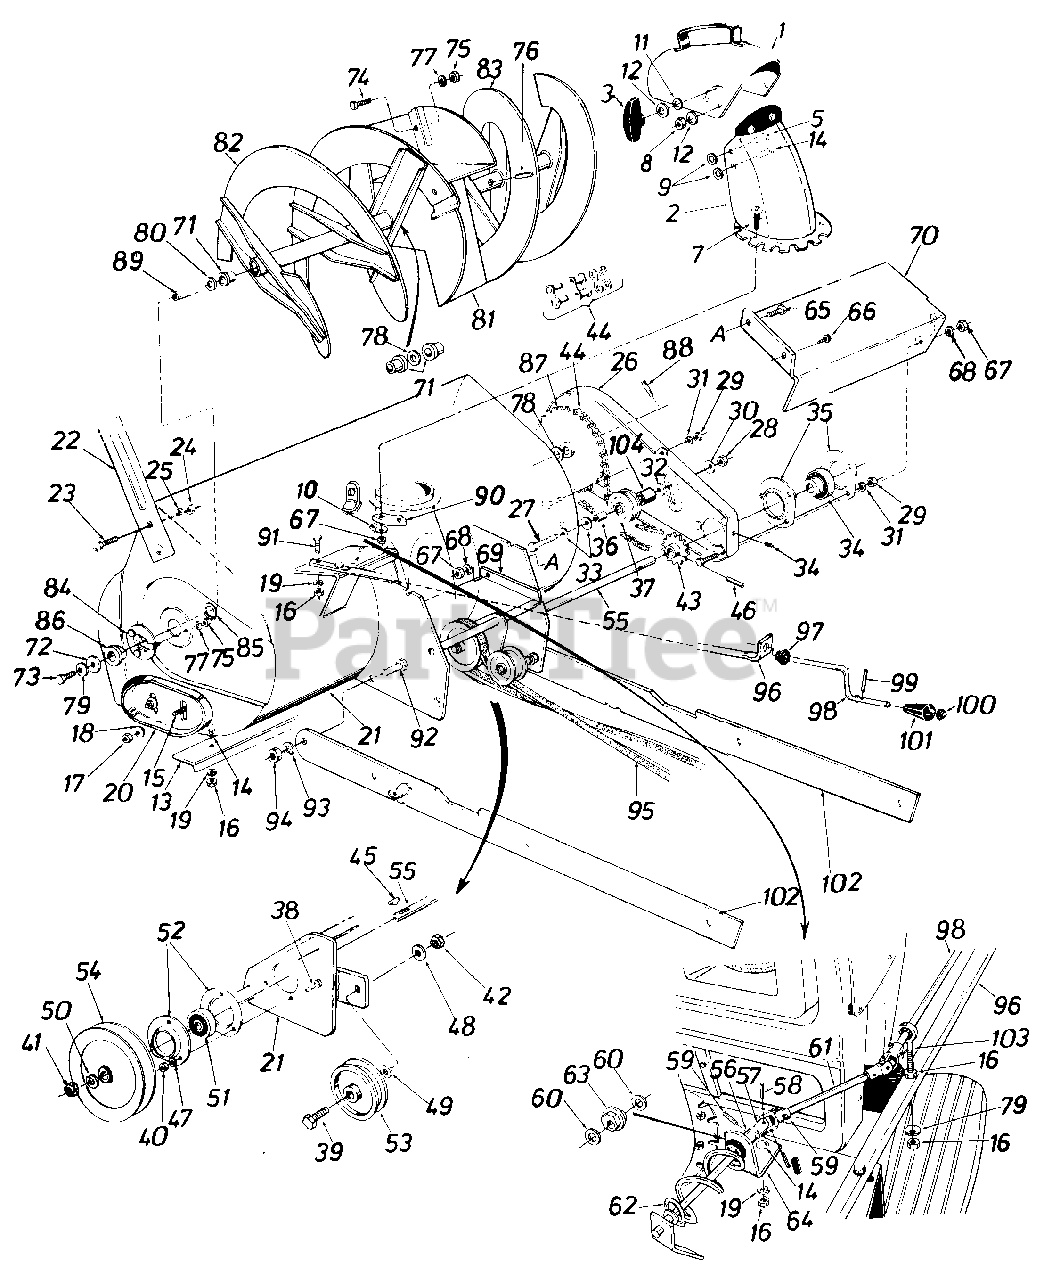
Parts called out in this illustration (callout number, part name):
1	Top Chute Ass'y.
2	Chute Assy w/ Guard
3	Knob Handle Ass'y,
5	Carriage Bolt 5/l6-18 x 1.0" Lg.'
7	Truss Mach. Scr. 1/4-20 x .75" Lg.
8	Hex Cent L-Nut 5/16-18 Thd.
9	Fl.Wash. 531" I.D. x 1.25" O.D.
10	Bell Wash 1/4" I D
11	Fl Wash 344 1 D x 1.125" o.D
12	Bell Wash. 345" 1 D. x .88" 0D.
14	Carriage Bolt 5/16-18 x .62" Lg.
15	Carriage Bolt 3/8-16 x .62" Lg.*
16	Hex Nut 5/16-18 Thd.'
17	Hex Jam Nut 3/8-16 Thd.
18	Bell. Wash. .400" I.D. x .88" O.D.
19	L. Wash. 5/16" I.D.'
20	Slide Shoe
21	Spiral Hsg. Ass'y.-36"
22	Guide Blade
23	Carriage Bolt 5/16-18 x .62" Lg.'
24	Hex Nut 5/16-18 Thd.'
25	L.-Wash. 5/16" I.D.'
26	Chain Guard Ass'y.
27	Hex Bolt 3/8-16 x 2.00 Lg.'
28	Hex Inst.-Nut 3/8-16 Thd.
29	Hex Nut 5/16-18 Thd.'
30	Bell.-Wash. .400" I.D. x .88 O.D.
31	L.-Wash. 5/16" I.D.'
32	Fl.-Wash. .406" I.D. x 1.25" O.D.
33	Fl-Wash. .385" I.D. x .87" O.D.
34	Ball Brg. .75" I.D.
35	Flangette
36	Spacer .375" I.D. x .60" O.D.
37	Fl.-Idler w/Flanges 1.875 O.D. Plastic
38	Hex Sems Bolt 5/18 x .75" Lg.
39	Hex Bolt 3/8-16 x 1.75" Lg.'
40	Hex Nut 5/16-18 Thd.'
41	Hex Jam Nut 3/4-10 Thd.
42	Hex Jam Nut 3/8-16 Thd.
43	Sprocket Ass'v.-14 Teeth
44	4420 Chain x 112" Pitch 78 Links
45	461 Hi- Pro-Key 3/16 x 518" Dia.
46	Spring Pin Spir. 5/16" Dia. x 1.75" Lg.
47	L.Wash. 5/16" 1 D.'
48	L.-Wash. 3/8" I.D.'
49	Fl.-Wash .406" 1 D x 125 ' O.D
50	Spring L.-Wash 314' I.D.
51	Self-Aligning Brg.
52	Flangette
53	Idler Pulley
54	5/8 V Pulley 75 ' ' D x 6.0"O.D.
55	Drive Shaft Assv
56	Joint Brkt. Ass'y
57	Joint Block
58	Oval Head Rivet
59	Spirol Pin 1/8 Dia x .812" Lg .
60	Fl.Wash .385 I.D. x .62" O.D.
61	Chute Crank Ext Rod 3/8" Dia. x 60 Lg
62	Chute Crank Ass y. R H 6-1/4 Lg
63	Plastic Bushing .380 1 D
64	Chute Crank Brkt
65	Hex Bolt 1/4 20 x .62" Lg '
66	Hex Wash S-Tap Scr 1/4 20 x -50" Lg
67	Hex Nut 1/4 20 Thd'
68	L-Wash- 1l4" 1 D'
69	Belt Cover
70	Drive Shaft Cover
71	Plastic Bushing
72	Washer 39' I-D x 1-,75" O-D
73	Hex Bolt 5/16-18 x -88" Spec
74	Carriage Bolt 5/16-18 x 75" Lg.*
75	Hex Nut 5/16-18 Thd'
76	Spring Pin Spiral 5/16" Dia- x 1.75" Lg
77	L-Wash. 5/16" I.D.'
78	Fl Wash 1-03" 1 D- x 162" O-D.
79	Bell-Wash- -345' I-D- x 88" O-D
80	Fl-Wash 10" I-D x 1-75" O-D.
85	Snap Ring for 1.50" Shaft
86	Flange Brg- w/flats 1-00" I-D
87	Sprocket Hub Ass'y. 40 Teeth
88	Spring Pin Spir 5/16 Dia. x 1.75" Lg
89	Spiral Axle
90	Chute Flange Keeper
91	Hex Bolt 5/16-18 x 1-5" Lg.'
92	Hex Bolt 1/213 x 125" Lg-'
93	L Wash- 1/2" 1 D'
94	Hex Nut 1/2"13 Thd.'
95	"V"Belt 1/2" "A" x 89.0" Lg
98	Chute Crank 375" Dia. x 34.5" Lg.
99	Roll Pin 12 Dia x .63"
100	Push Nut 3/8" Rod
101	Knob Black
102	Linkage Arm
103	Eye Bolt 5/16-18 x 3.0" Lg.
104	Idler Spacer 377 I.D. x 624 OD x 840
